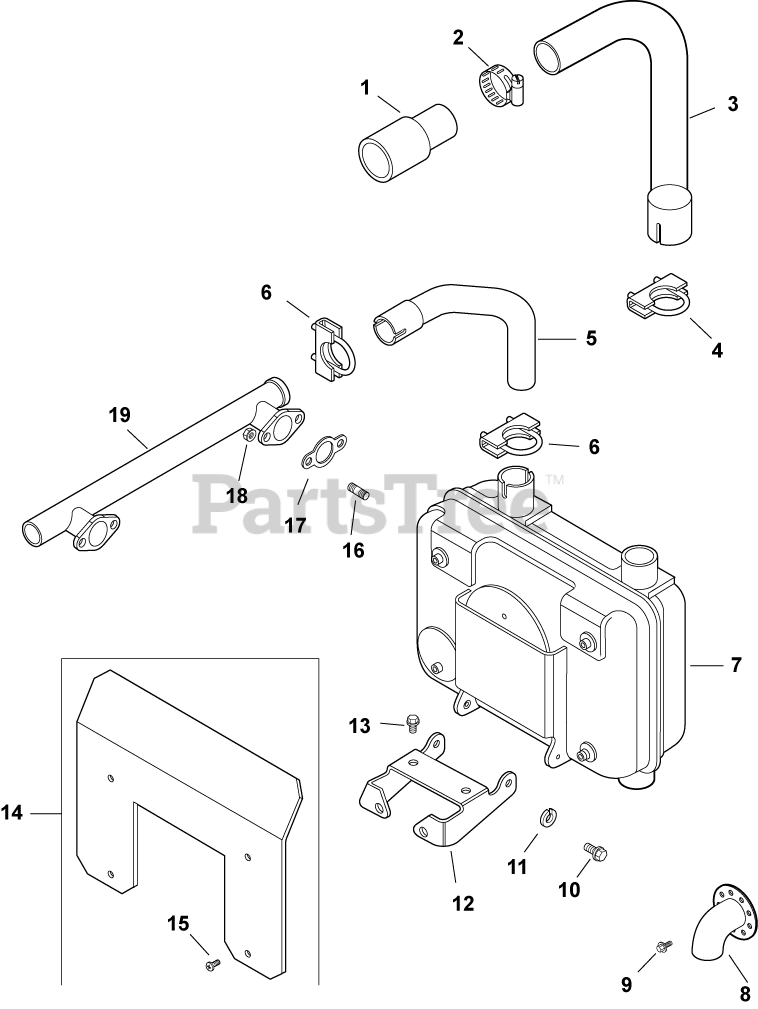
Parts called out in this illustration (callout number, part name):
1	HOSE, STEP
2	CLAMP, HOSE
3	TUBE, CONNECTOR - USE 24 123 26-S
4	CLAMP, MUFFLER
5	PIPE, EXHAUST
6	CLAMP, MUFFLER
7	MUFFLER, SIDE MOUNT USE 24 068 155-S
8	DEFLECTOR, EXHAUST - USE 12 265 09-S
9	SCREW, SEMS DRILL #8-18X1/2"
10	BRACKET, MUFFLER
11	WASHER, SPRING LOCK 1/4"
12	SCREW,FLG THD FRM M6X1.0X16-(#25086397S)
13	SCREW, FLG M8X1.25X20
14	KIT, HEAT SHIELD
15	SCREW, HVY FLG M5X.8X10
16	STUD, EXHAUST-USE 25 072 24-S
17	GASKET, EXHAUST
18	NUT, FLG M8X1.25
19	MANIFOLD, EXHAUST
